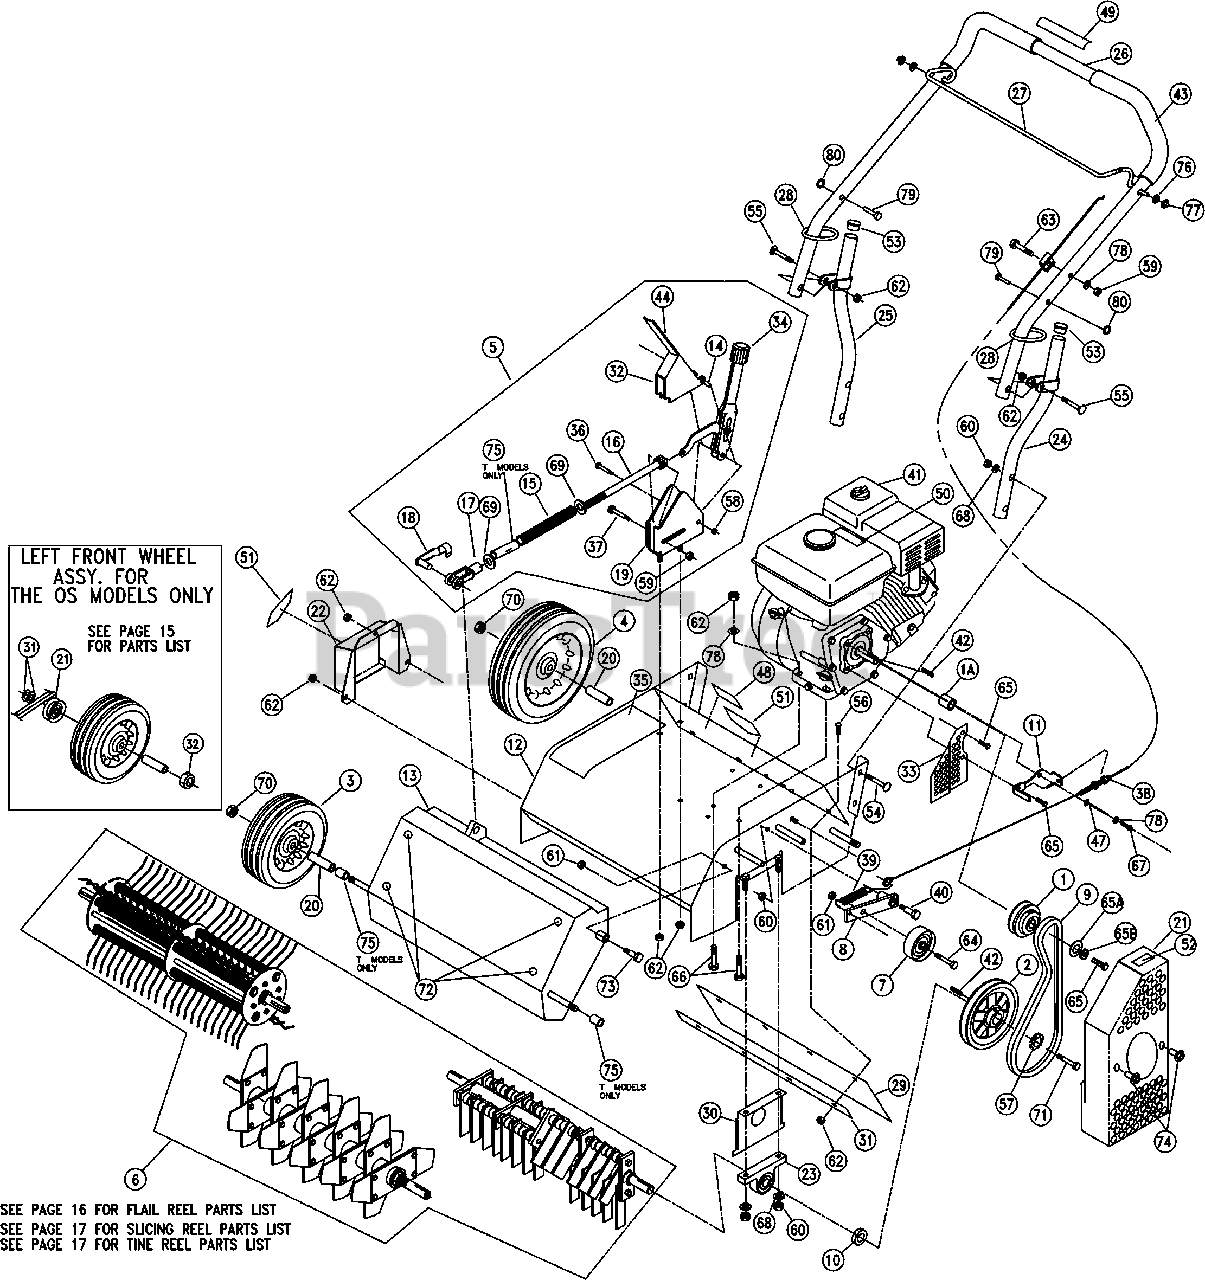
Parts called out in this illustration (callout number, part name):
1	Pulley 3" OD
1A	Spacer Crank PR Honda
2	Pulley 6.5" OD X ¾"
3	WHEEL 8.0" X 5/8" BEARING
4	WHEEL 10.0" X 5/8" BEARING
5	Height Adjust Assy
6	Reel Flail / Slicing / Spring Assy
7	Pulley Idler 2.75"
8	Arm Idler WA
9	Belt 5L X 36
10	Spacer Reel Pulley
11	Bracket Mount Clutch Cable
12	Chassis WA W/ Label
13	Frame Front WA
14	Bushing 0.375 OD X 0.256 ID X 0.88
15	Spring Height Adjust PR500
16	Link Height Adjust PR500
17	Yoke ½ - 20
18	Pin Yoke ½"
19	Bracket Mount Hgt. Adj. WA
20	Spacer Spanner Wheel PR500
21	Guard Belt WA W/ Label
22	Guard Shaft WA W/ Label
23	Bearing ¾" Cast Pillow Block
24	Handle Lower LH WA
25	Handle Lower RH WA
26	Handle Upper PR500
27	Bail Clutch WA
28	Loop Folding Handle
29	Deflector Rubber
30	Shield Bearing
31	Bar Clamp Deflector
32	Bracket Height Adjust Lock WA
33	Guard Pulley Back
34	Lever Height Control
35	Label Instr. Hgt. Adj.
36	Bolt Shoulder ¼" x 1 ¾"
37	Bolt Shoulder 5/16" x 1 ¾"
38	Cable Clutch Reel PR500
39	Spring Extension
40	BOLT SHOULDER 1/2" X 1"
41	ENGINE HONDA 5.5 H.P. GX160
42	KEY 3/16" X 1"
43	GRIP 1" x 13"
44	GRIP LEVER 1/8 x 1 x 5"
45	LABEL INSTRUCTION SEEDER BOX
46	FINGER BELT WIRE
47	LABEL DANGER THROWN OBJECT
48	LABEL CLUTCH VQ
49	LABEL HOT ENGINE
50	LABEL WARNING
51	LABEL DANGER GUARD
52	PLUG CAP 1" RD
53	BOLT CARRAIGE 3/8-16 x 1 3/4
54	BOLT CARRAIGE 5/16-18 x 1 3/4
55	BOLT CARRIAGE 5/16 -18 x 3/4
56	LOCK WASHER TW. TOOTH
57	NUT LOCK #10-24
58	NUT LOCK 1/4-20
59	NUT LOCK 3/8-16
61	NUT LOCK 3/8-16 THIN
62	NUT LOCK 5/16-18
63	SCREWCAP 1/4-20 x 1 1/2
64	SCREWCAP 3/8 - 16 x 1 1/2
65	SCREWCAP 5/16-24 x 3/4" GR.5
65A	Washer 3/4 SAE
65B	Washer 5/16 Twist Tooth
66	SCREWCAP 5/16 - 18 x 1 1/2
67	SCREWCAP 5/16-24 X 1
68	WASHER 3/8 FLAT CUT
69	WASHER 1/2 SAE ZP
70	NUT LOCK 1/2" - 13 THIN HGT
71	SCREWCAP REEL PULLEY
72	PART NOT APPLICABLE ON THIS MODEL
75	PART NOT APPLICABLE ON THIS MODEL
76	WASHER 3/8 SAE
77	NUT PAL 3/8
78	WASHER 1/4 FLAT CUT
79	PIN CLEVIS 3/8" X 1.625
80	RETAINER 3/8" BOLT PUSH NUT
